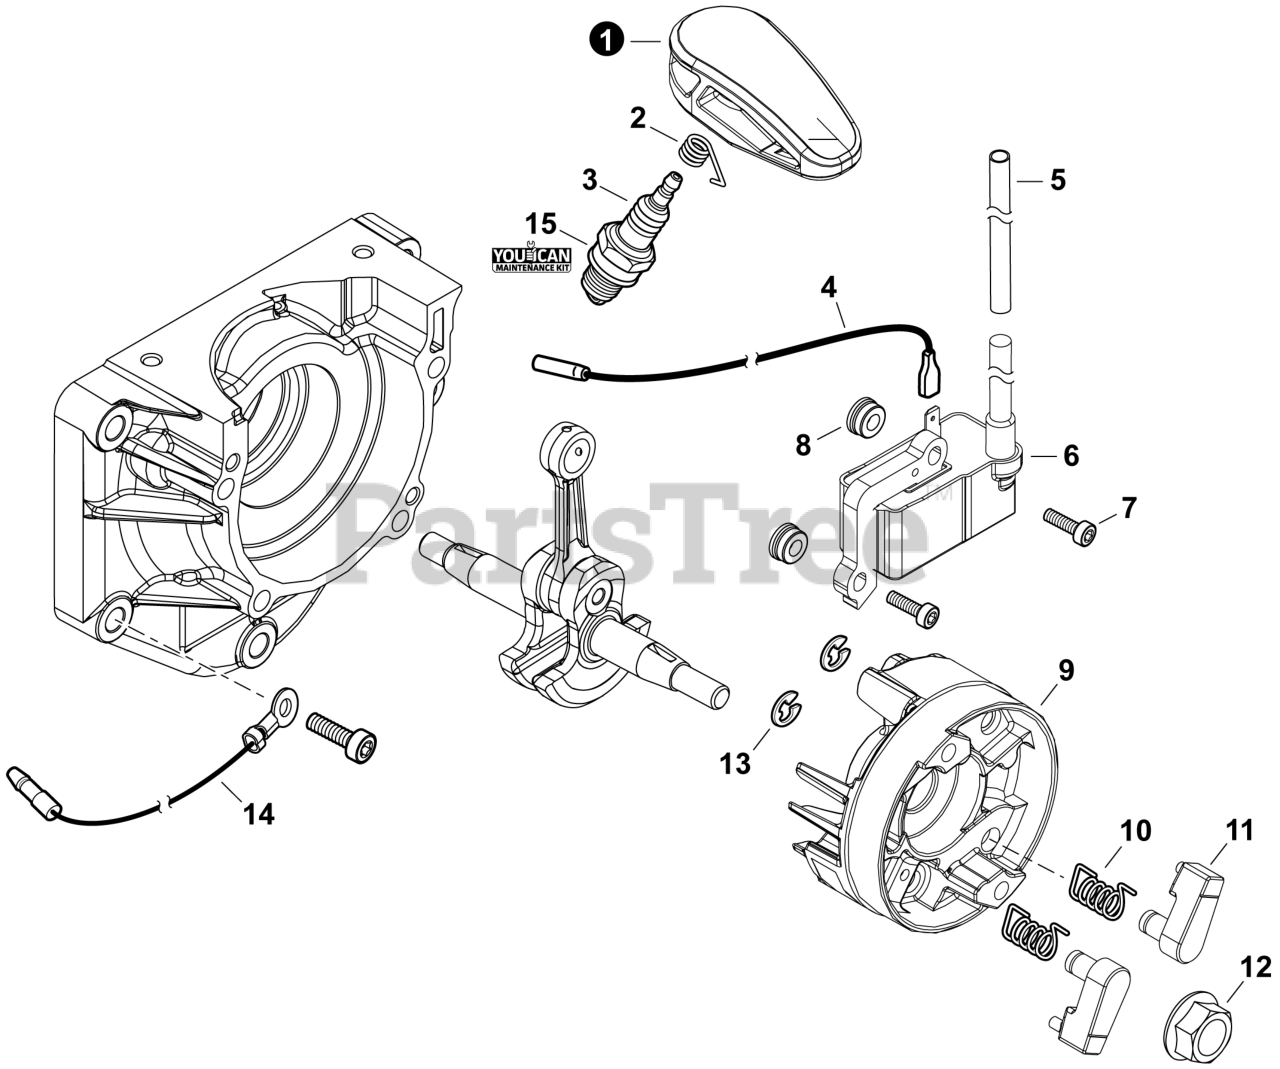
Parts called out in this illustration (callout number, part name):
1	CAP, SPARK PLUG
2	TERMINAL, SPARK PLUG
3	SPARK PLUG - CMR7H
5	TUBE, INSULATOR
6	COIL, IGNITION
7	BOLT 4×20
8	COLLAR 4
9	FLYWHEEL
10	SPRING, RETURN
11	PAWL, STARTER
12	NUT, FLANGE 10×1.25
15	TUNE-UP KIT - YOUCANT
